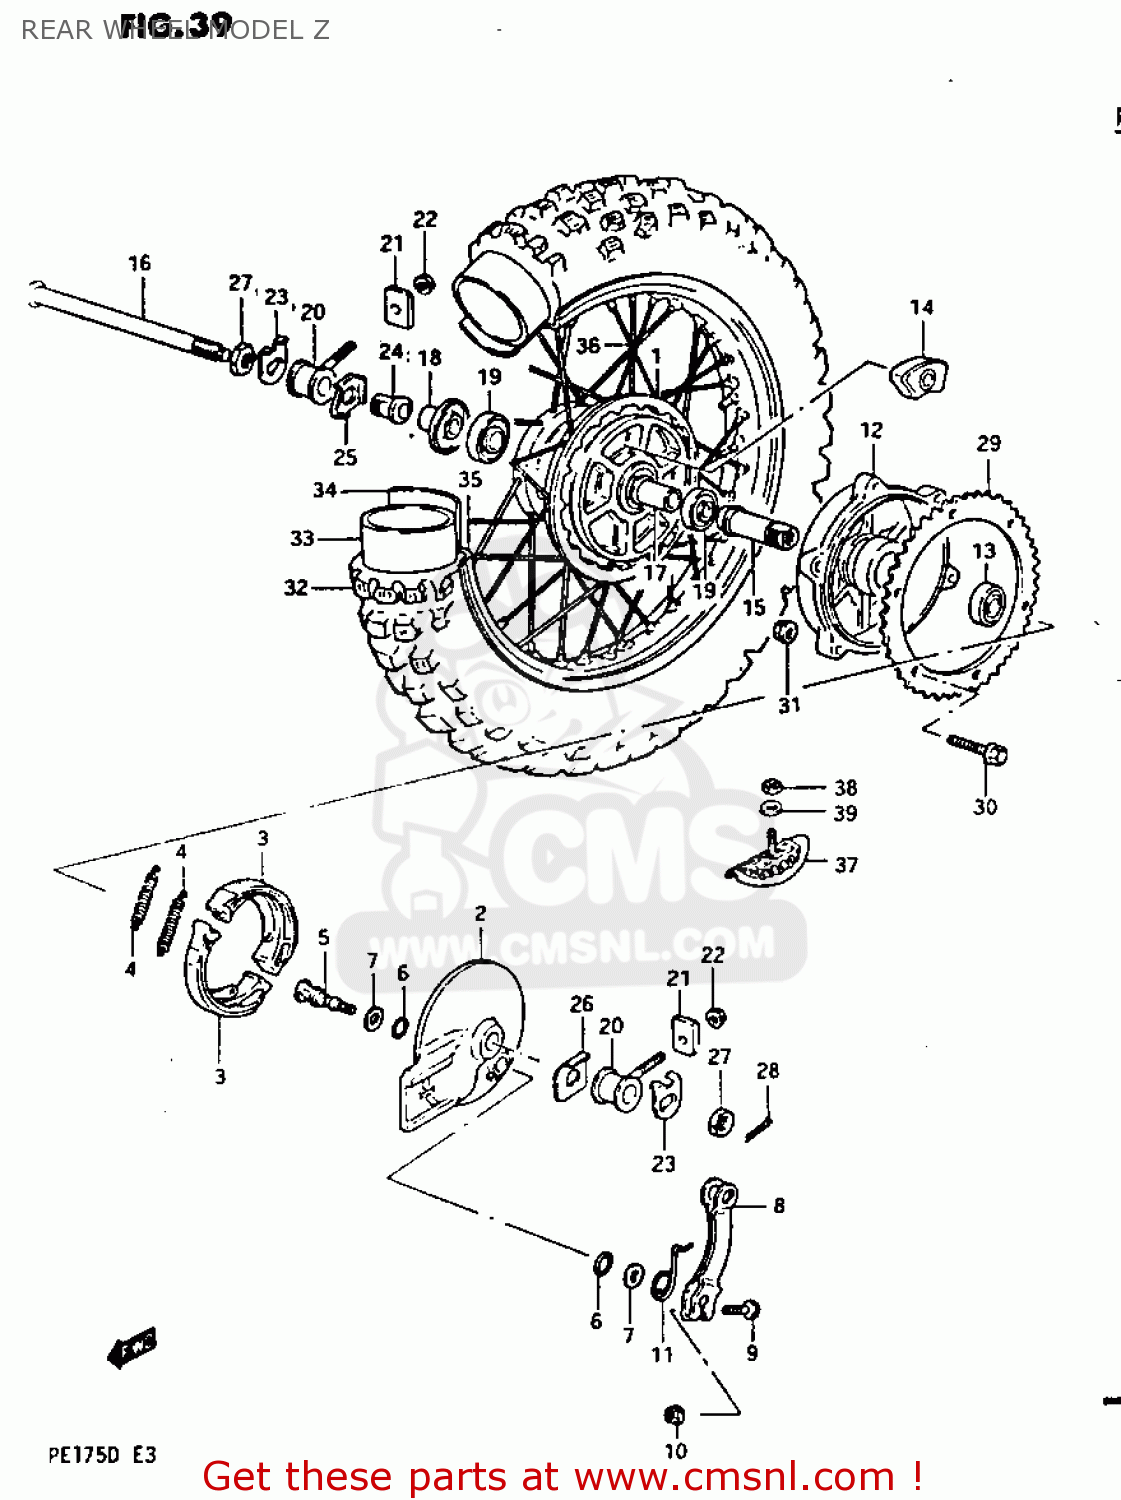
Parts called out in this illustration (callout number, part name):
1	HUB,REAR WHEEL
2	PANEL,REAR HUB
3	SHOE,BRAKE
4	SPRING(L:35.8)
5	CAM,REAR BRAKE
6	O-RING (D:2.4 ID:13.8)
7	WASHER (14.5X22X1.6)
8	LEVER,REAR BRAKE CAM
9	BOLT
10	NUT
11	SPRING
12	DRUM ASSEMBLY,REAR BRAKE
13	BALL BEARING 22X50X14
14	ABSORBER,RR HUB SHOCK
15	SHAFT,REAR BRAKE DRUM
16	AXLE,REAR
17	SPACER,REAR HUB BEARING
18	SPACER,REAR AXLE,RIGHT
19	BEARING
20	ADJUSTER,CHAIN
21	PLATE,CHAIN ADJUSTER GUIDE,R
22	NUT
23	WASHER,CHAIN ADJUSTER GUIDE
24	SPACER,CHAIN ADJUSTER
25	PLATE,CHAIN ADJUSTER,RIGHT
26	PLATE CH ADJUSTER LH
27	NUT
28	PIN 30X20
29	SPROCKET,REAR (NT:48)(AL)
30	BOLT(8X30)
31	NUT
32	TIRE
33	TUBE ASSEMBLY,WHEEL,INNER
34	PROTECTOR,INNER TUBE
35	RIM,REAR WHEEL
36	SPOKE SET,REAR
37	STOPPER,BEAD
38	NUT
39	WASHER
